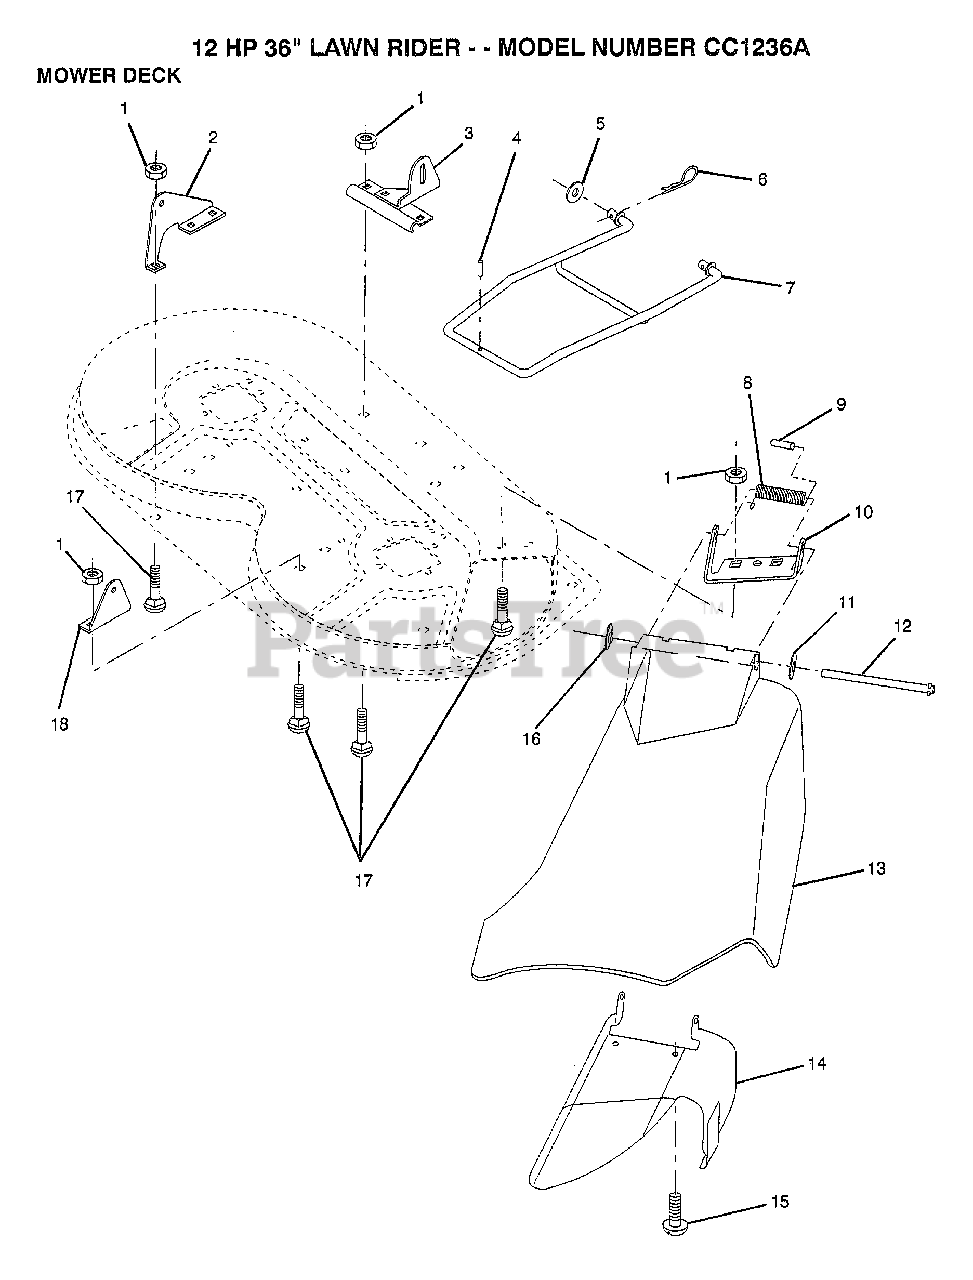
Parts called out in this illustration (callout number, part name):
2	"BRKT,LIFT REAR LH"
3	"BRKT,LINK STABILI"
4	"PIN,GROOVE"
6	RETAINER.SPRING
7	MOWER LINK STAB
8	SPRING TORSION
9	CAP-SLEEVE LT
11	WASHER
12	HINGE ROD
14	DEFL SUPT ASS'Y
15	SCREW PAN HD
16	NUT PUSH M
17	BOLT
18	"BRKT,LIFT REAR"
